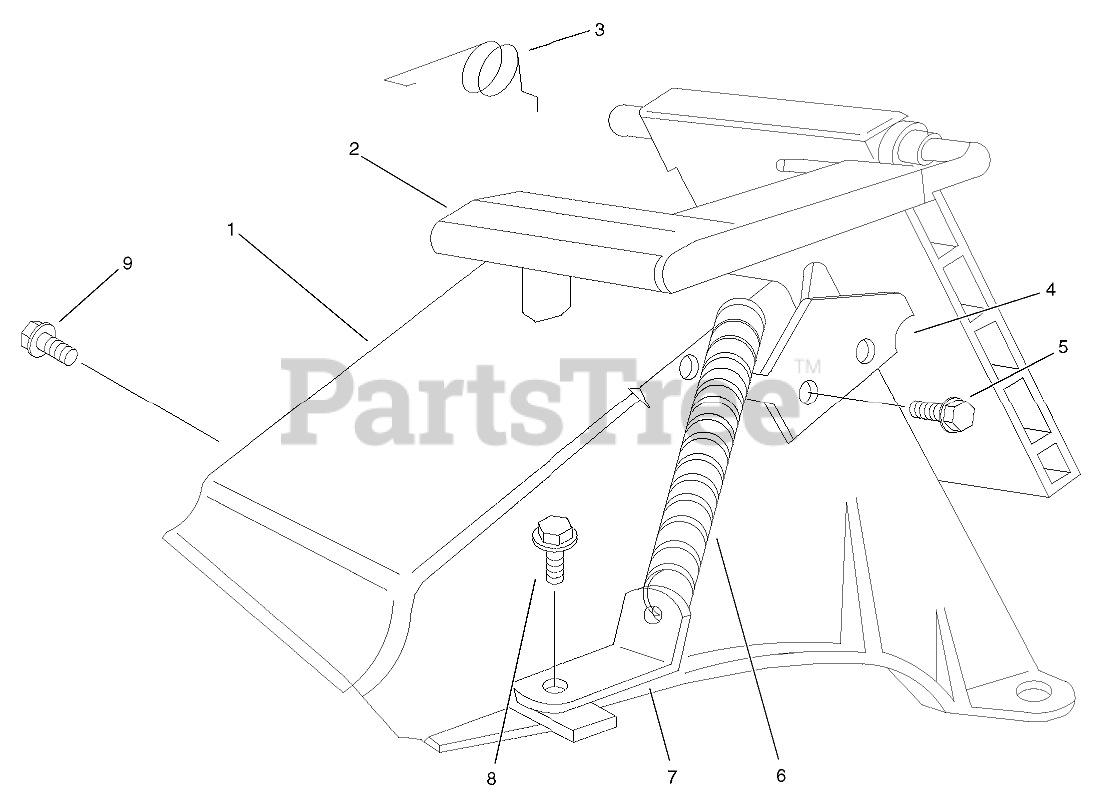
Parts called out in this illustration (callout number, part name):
1	TUNNEL-DISCHARGE
2	DISCHARGE DOOR ASM
3	SPRING-DOOR
4	LATCH-PLATE
5	SCREW-PLASTITE
6	RETAINER-DOOR
7	BRACKET-SPRING
8	SCREW-HWH
9	SCREW AND WASHER ASM
